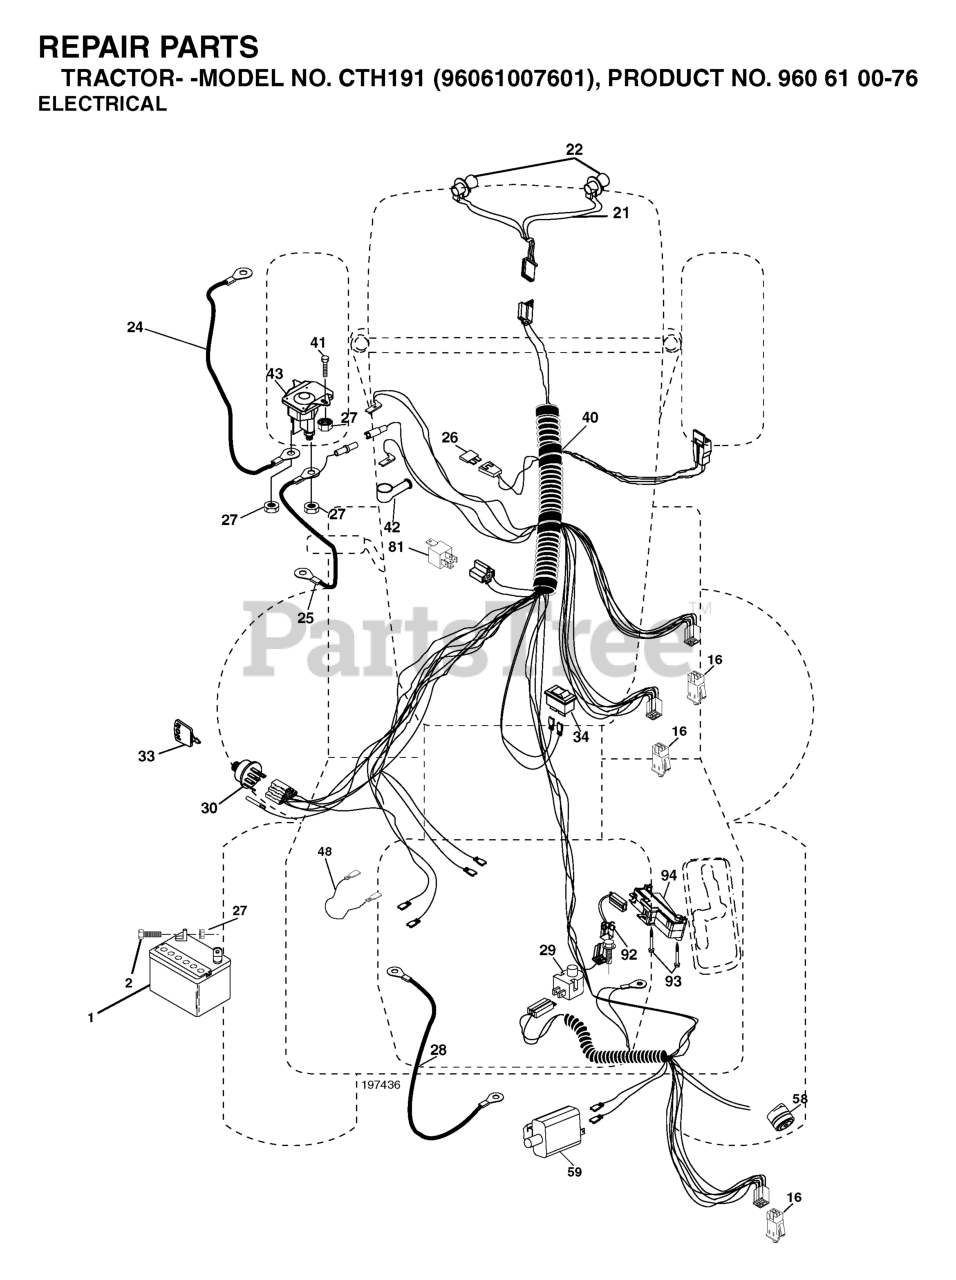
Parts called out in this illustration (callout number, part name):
1	BATTERY 12V .35 AMP
2	BOLT.HEX.1/4.X.3/4.DICHROMATE
16	SWITCH INTERLOOK PUSH-IN
21	HARNESS.W/LIGHT SOCKET
24	BATTERY CABLE GT
25	CABLE BATTERY
26	FUSE 20AMP
27	NUT
28	CABLE GROUND
29	SWITCH.SEAT.DP W/RAMPS
30	SWITCH.IGN.DELTA.W.LGH.ROS
33	KEY MLD GEN DELTA
41	BOLT
42	TERMINAL COVER
43	SOLENOID.W/BRASS.PLUNGER
48	ADAPTER.AMMETER
58	BUZZER
59	.WITCH.FULL BAGGER.INDICATOR
81	RELAY.ASSY.T
92	HARNESS.PIGTAIL.CONSLE
93	SCREW.PLASTITE
94	MODULE.REVERSE.ROS
